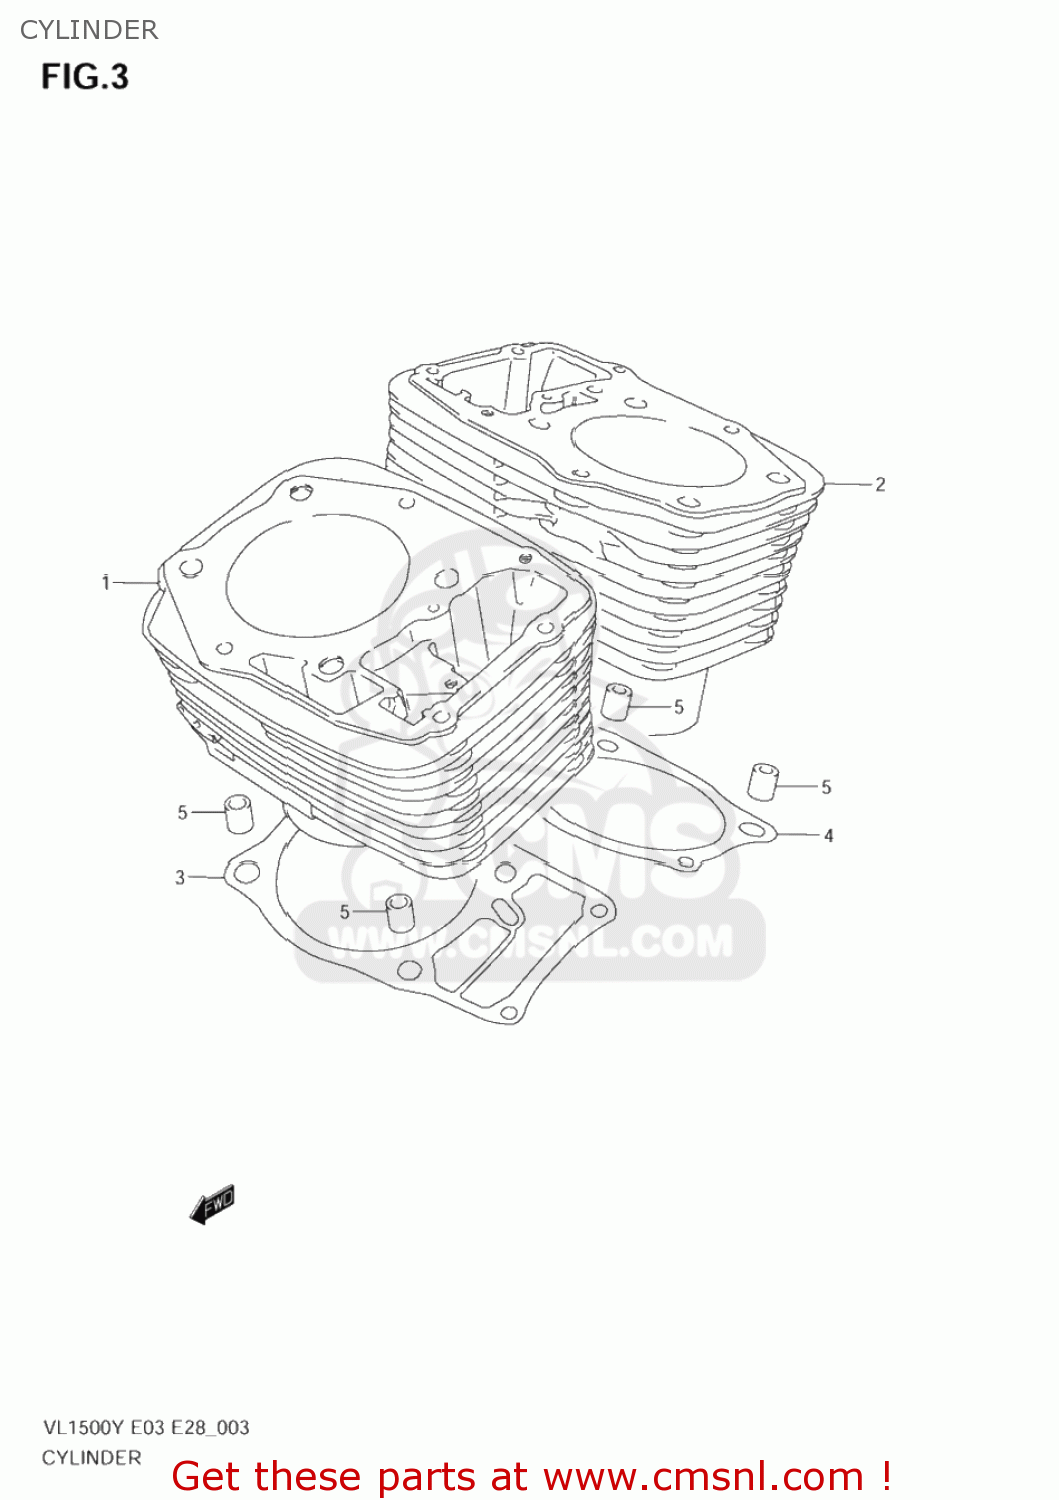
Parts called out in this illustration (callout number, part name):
1	CYLINDER,FR
2	CYLINDER,RR
3	GASKET,CYLINDER FR (NAS)
4	GASKET,CYLINDER RR (NAS)
5	PIN
